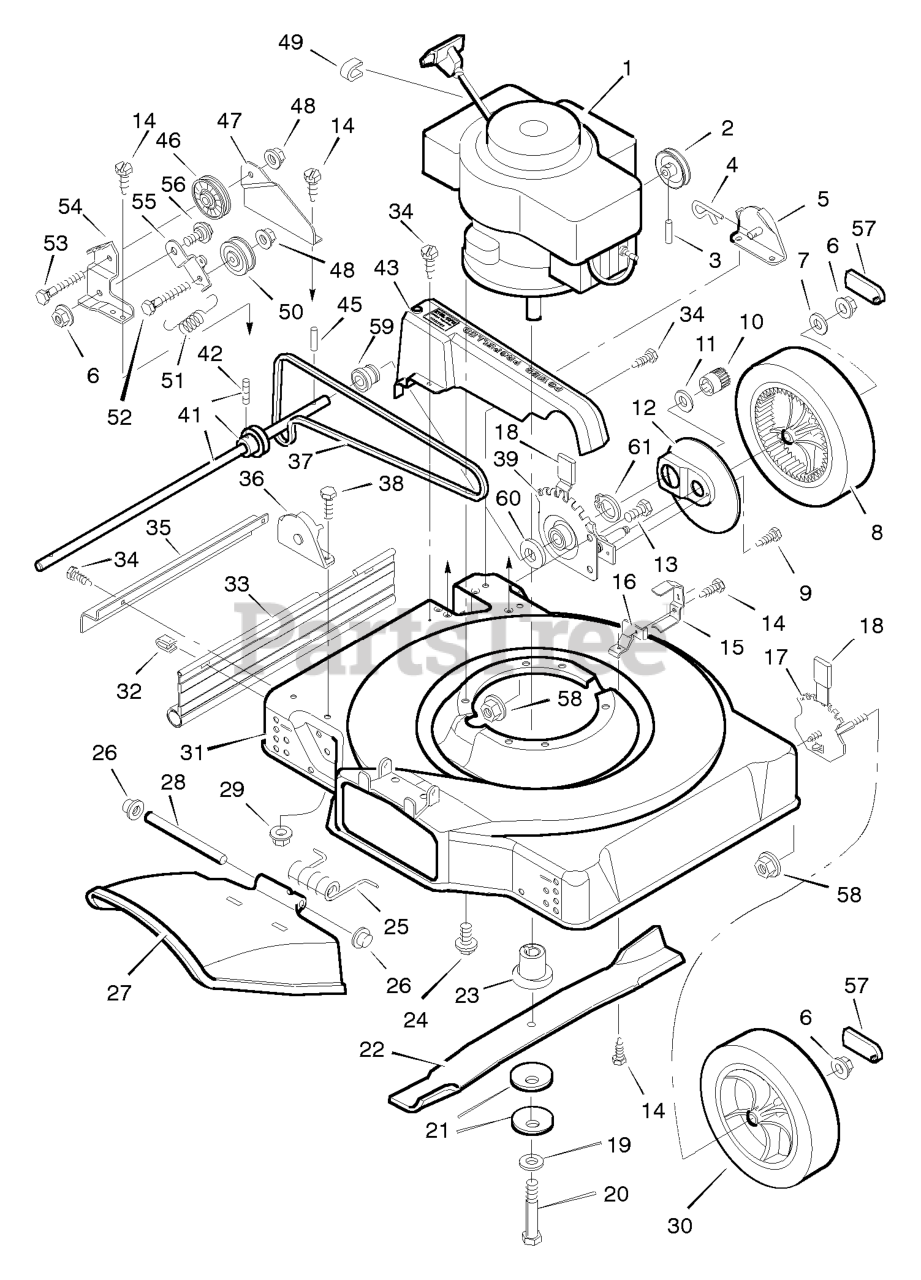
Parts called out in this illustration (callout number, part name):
1	Engine *
3	Pin, Spring
4	Pin, Hair
5	Bracket, Left Handle
6	Nut
7	Washer
8	Wheel, Drive
10	Gear, Right Pinion
12	Cover, Dust
13	Bolt, Hex
15	Guide, Belt
16	Belt Guide, Briggs
17	Height Adjuster, Front
21	Washer, Belleville
23	Adapter, Blade
24	Bolt, Engine
25	Spring, Torsion
26	Push On Cap
27	Deflector, Chute
29	Nut
30	WHEEL & TIRE ASSEMBLY, White, 8"
31	Housing
32	Retainer
33	Deflector, Rear
35	Guard, Axle
36	Bracket, Right Handle
37	Belt, Briggs & Stratton
39	Height Adjuster, Left
41	Axle, Pulley & Setscrew
42	Setscrew
43	Belt Guard, Briggs
45	Pin, Drive
46	Pulley, Idler
47	Support, Idler
48	Nut
49	Stop, Rope
50	Pulley, Idler
51	Spring, Extension
52	Bolt, Hex
53	Bolt, Hex
54	Bracket, Idler
55	Arm, Idler
56	Bolt, Shoulder
57	Cap, Hub
58	Nut, Flange
59	Bearing and Retainer
60	Washer, Belleville
61	Retainer Ring
